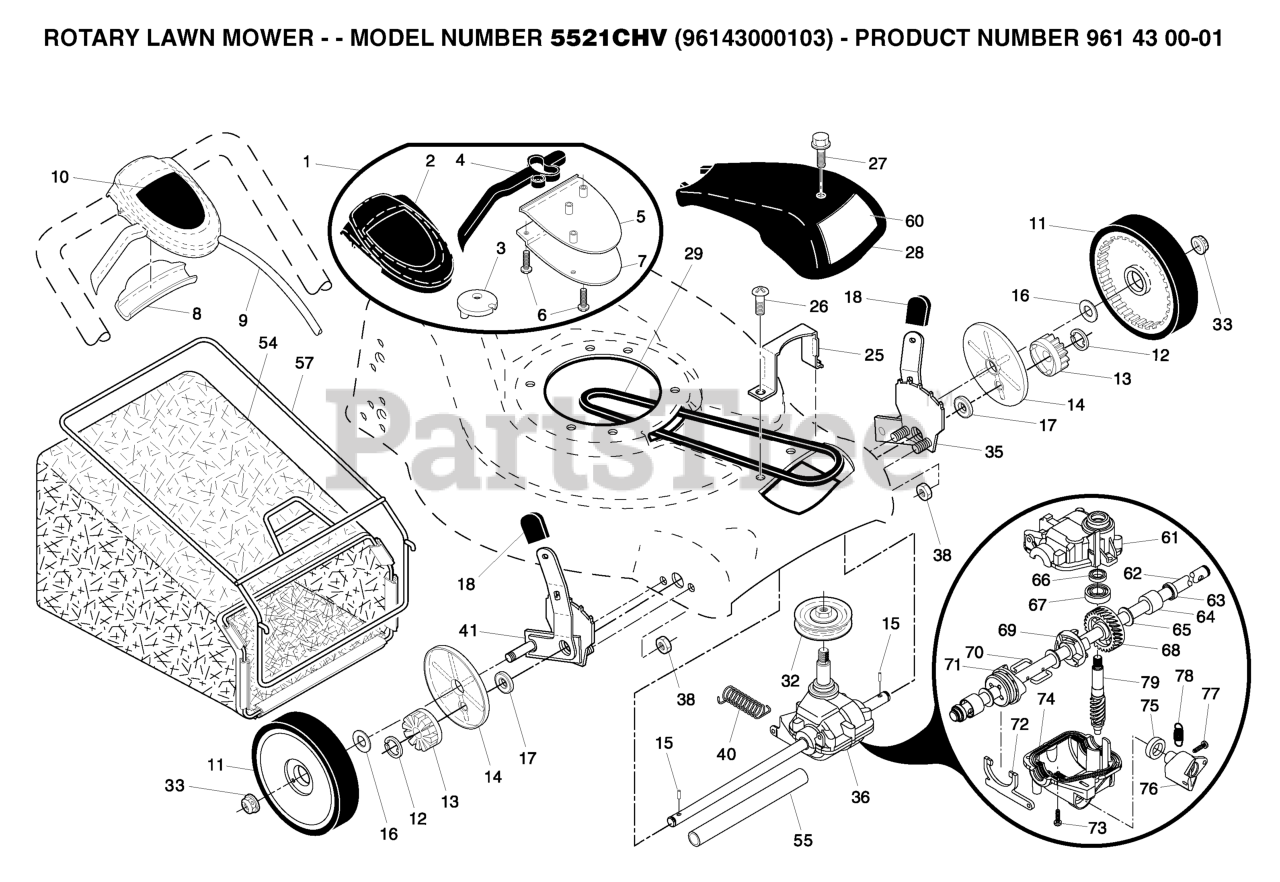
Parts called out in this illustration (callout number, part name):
1	CONTROL.DR.EZ.FWGD.SHORT.GY/BL
2	CASE.TOP.GRAY
3	PULLEY.CAM.DRIVE.CONTROL.HV
4	LEVER, AUTOWALK DRIVE CONTROL
5	CASE BOTTOM
6	SCREW, PHILLIPS HEAD 10 X 5/8
7	BRACKET.DRIVE.CONTROL.MOUNT.BL
8	EZ WALK SNAP COVER PLATE
9	CABLE.ASM.
10	DECAL.DRIVE.CONTROL.HV
11	WHEEL.8X1.75.5SPK.RAD.GREY
12	E-RING 7/16 RE
13	PINION
14	COVER.DUST.WHEEL
15	PAWL.DRIVE
16	WASHER FLUT
17	BEARING
18	SELECTOR KNOB
25	KEEPER.BELT.21.EZ.FWGD
26	SELF-TAPPING SCREW 5/16-18X3/4
27	SCREW, HEX HD TAPPING #10-24 1
28	COVER.DRIVE.21.FWGD.GRAY
29	BELT.DRIVE.FGD.
32	RP PULLEY.DRIVE.EZ
33	HEX FLANGE LOCKNT
35	RP KIT.ADJUSTER.ASM.EZ
36	TRANSMISSION.21RD
38	LOCKNUT.NYLOC.1/4-20
40	SPRING RETURN
41	KIT.ADJUSTER.AS.EZ RT
54	GBAG.34710247.SILVER.H
55	DRIVESHAFT COVER
57	FRAME.GBAG.21.FWGD.
61	GEARCASE.HOUSING
62	SHAFT.OUTPUT
63	SEAL.OUTPUT.SHAFT
66	SEAL INPUT SHAFT
68	GEAR.27.TEETH.WALK.MOWER
70	WIRE, FORMED (15966)
74	GEARCASE.HOUSING.LOWER
77	SCREW.LEVER.
79	SHAFT INPUT (13041)
